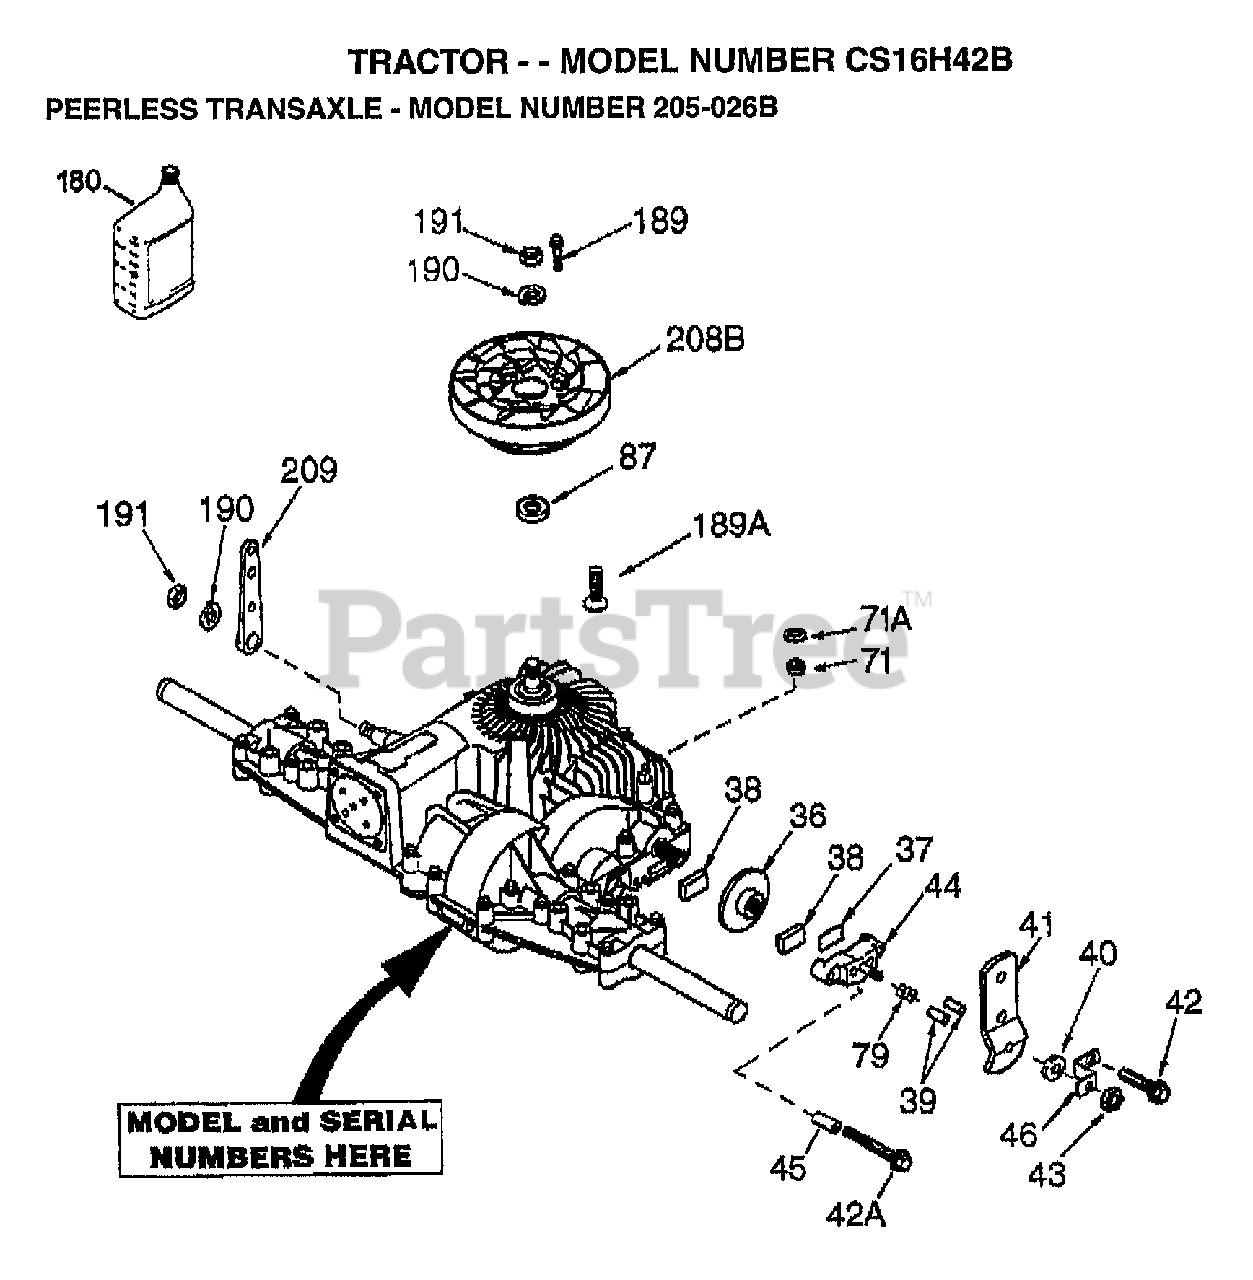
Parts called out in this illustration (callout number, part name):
37	PLATE BRAKE PAD
41	BRAKE LEVER
42	SCREW, 1/4-20 X 1-1/4
42A	SCREW, 1/4-20 X 2-1/4
43	LOCKNUT 5/16-24
44	HOLDER BRAKE PAD
46	BRAKE LEVER BRACKET
71	SEAL SQUARE CUT
180	GEAR OIL 80W90
189	DRIVE SCREW
208B	FAN/COUPLING
209	CONTROL LEVER
